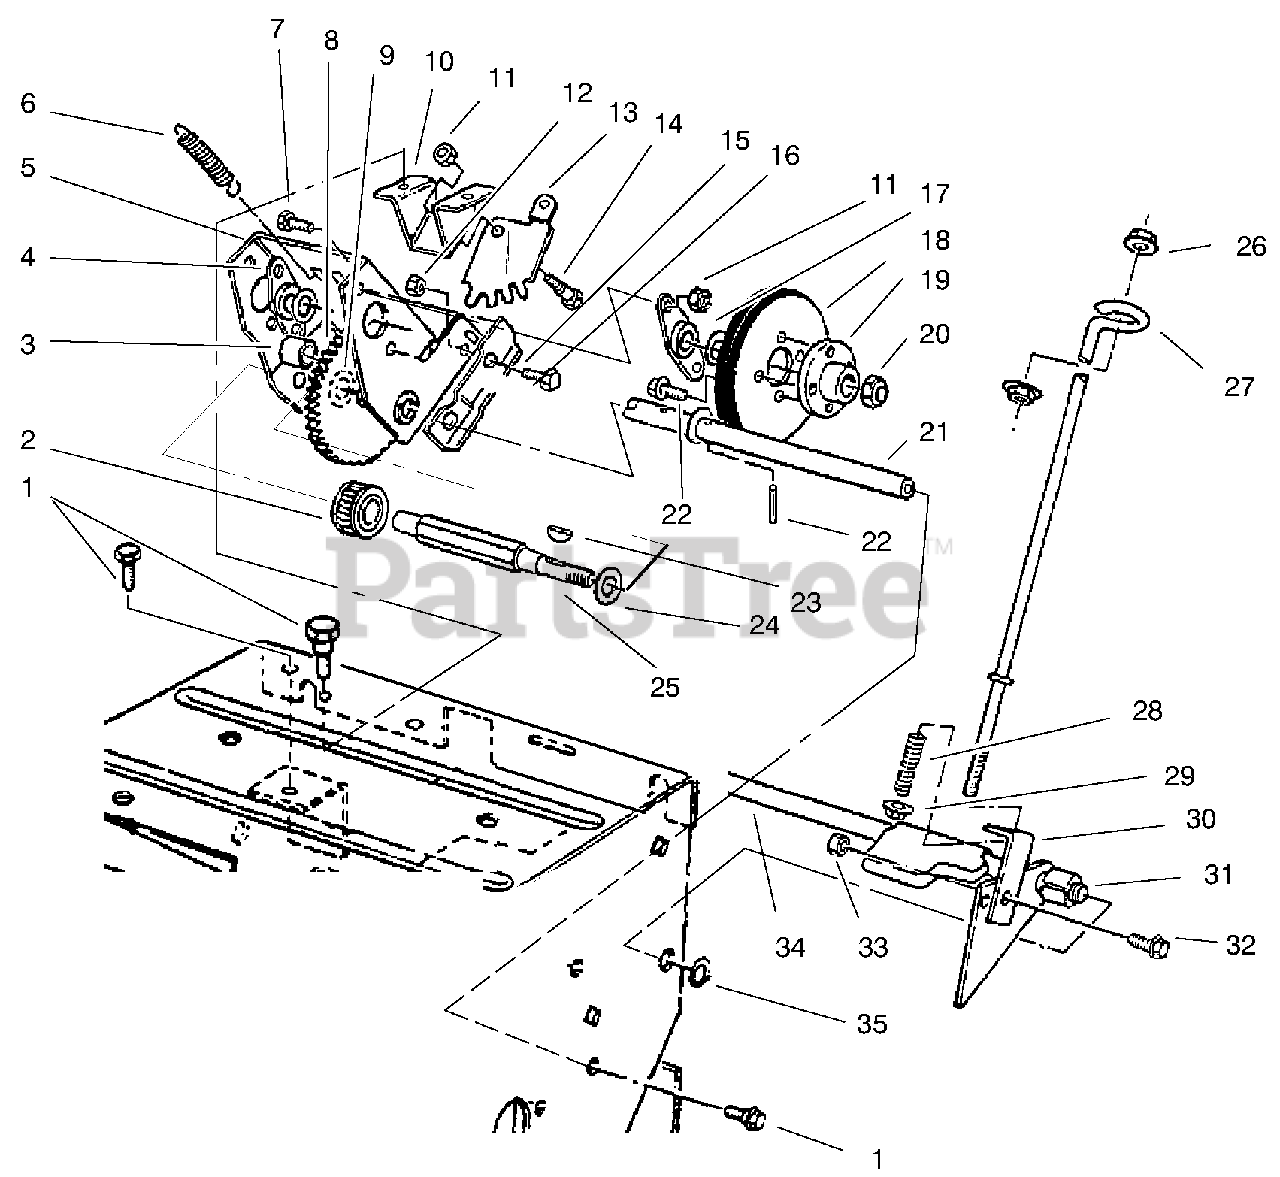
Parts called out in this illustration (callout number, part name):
1	Screw-Self Tap. Hex. Hd.
2	Gear-Sliding
3	Bushing
4	Bearing-Friction Wheel
5	Bracket-Sliding
6	Spring-Traction Engage
7	Screw-Hex. Hd.
8	Intermediate Gear & Bushing (Incl. Ref. #4)
9	Washer-Thrust
10	Mount-Quadrant Gear
11	Nut-Lock
12	Nut-Lock
13	Quadrant-Gear
14	Bolt-Shoulder
15	Cam-Receiver
16	Screw-Hex. Hd.
17	Washer-Thrust
18	Wheel-Friction
19	Hub-Friction Wheel Mount
20	Nut-Lock
21	Shaft-Pivot
24	Washer-Thrust
25	Shaft-Hex
26	Nut-Flange
27	Rod-Lower Traction
28	Spring-Compression
29	Nut-Flange
30	Bracket-Traction
32	Screw-Shoulder
33	Nut-Lock
34	Traction Engagement Asm.
35	Ring-Retaining
